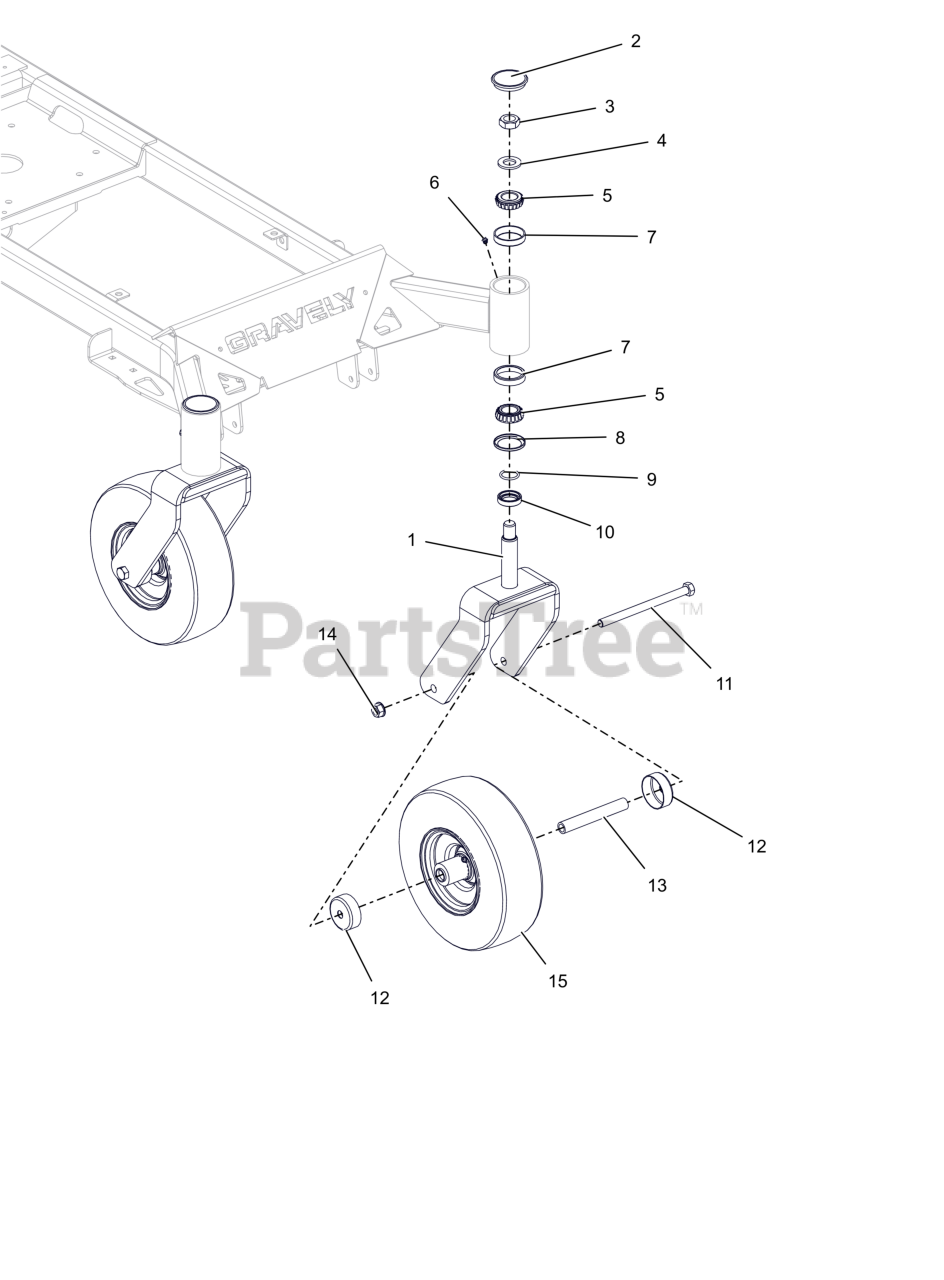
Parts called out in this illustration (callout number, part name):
1	WLDMT, CASTER FORK
2	CAP, DUST
3	NUT, JAM-TOPLOCK .750-16 ZCC
4	WSHR-FL-STL 0.812X1.469X0.134 ZCC
5	BRG-CONE 1.0X.58
6	FTG, .25-28 FLUSH MNT GREASE
7	BRG-CUP1.980X.420
8	BEARING SEAL 1.5 X 2 X .18
9	O-RING 1.000X1.250X
10	SPCR, CASTER FORK (1.00)
11	BLT, HEX 0.5-13X7 GR5 ZCC
12	SHIELD, WHEEL BEARING
13	SPACER, ROLLED WHEEL
14	NUT-LK-CTR-FLG .500-13 GG ZCC
15	ASM, WHL/TIRE 11X4.00-5
